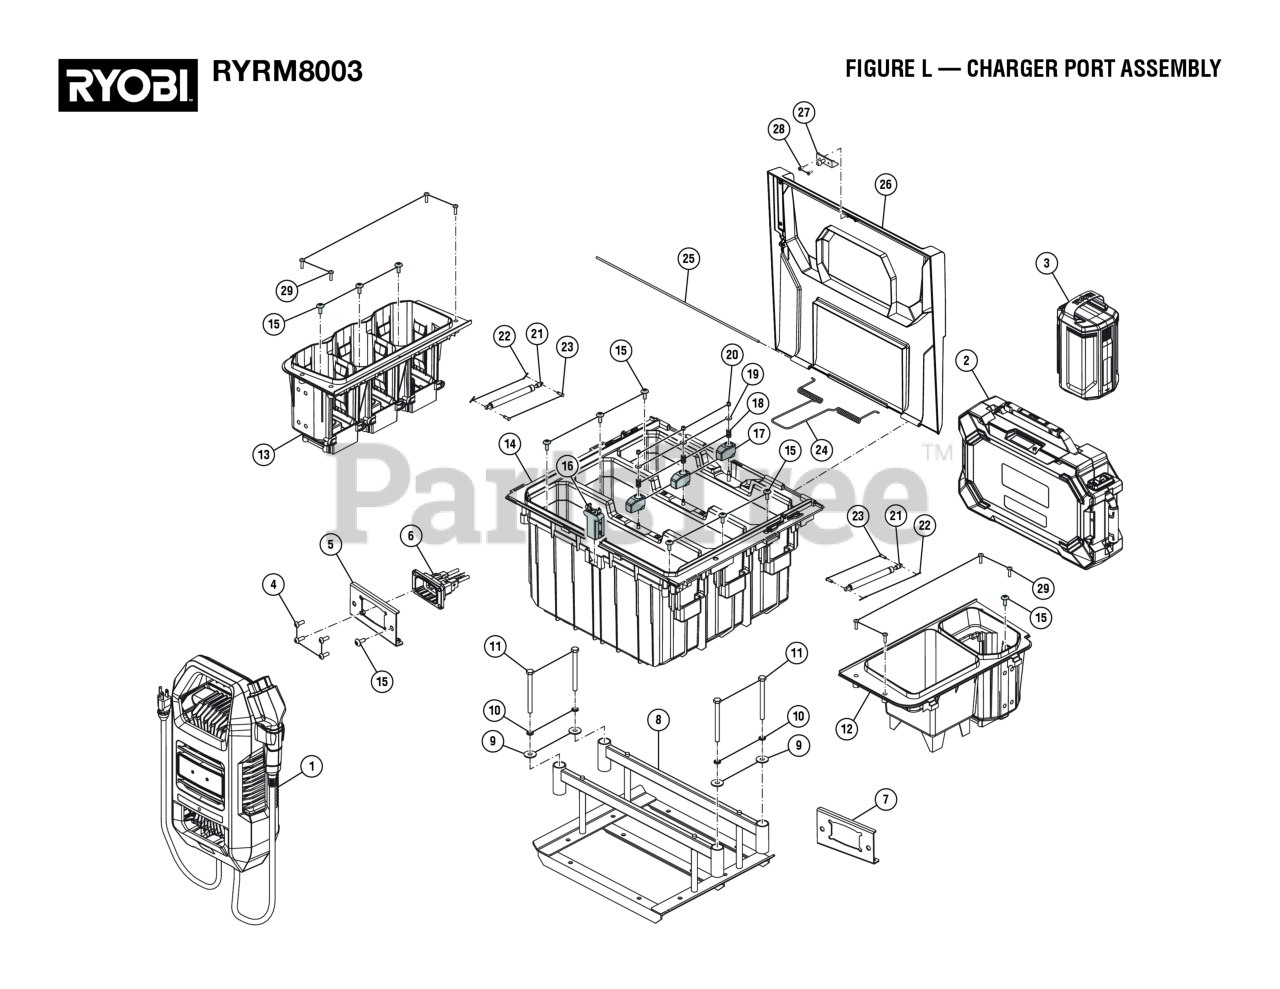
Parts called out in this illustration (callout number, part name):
1	Charger, 120V-AC (1440W, 90V-DC)
2	80V Battery Pack (720Wh)
3	40V Battery Pack (12Ah)
4	Screw (M6 x 16 mm, Torx Hd.)
5	Charging Port Mount
6	80V Charging Receptacle
7	Mount Plate (Right)
8	Battery Compartment Frame
9	Washer (OD 24 x ID8.4 x 2t)
10	Lock Washer (OD9.8 x ID8.5 x 5t)
11	Bolt (M8 x 90 mm, Hex Hd.)
12	40V Battery Bucket (Right)
13	40V Battery Bucket (Left)
14	80V Battery Bucket Assembly
15	Screw (M6 x 10 mm, Soc. Button Hd.)
16	Push-To-Open Switch
17	Battery Retainer
18	Battery Retainer Spring
19	Washer (OD12 x ID4.3 x 1t)
20	Nut (M4 x 0.7, Lock)
21	Battery Compartment Shock
22	Cotter Pin
23	Damper Pin
24	Torsion Spring
25	Compartment Lid Pin
26	80V Battery Lid
27	Battery Cover Lock
28	Lock Block Screw
29	SCREW,PPHMS, M5 X 0.8 X 16 - STEEL,
